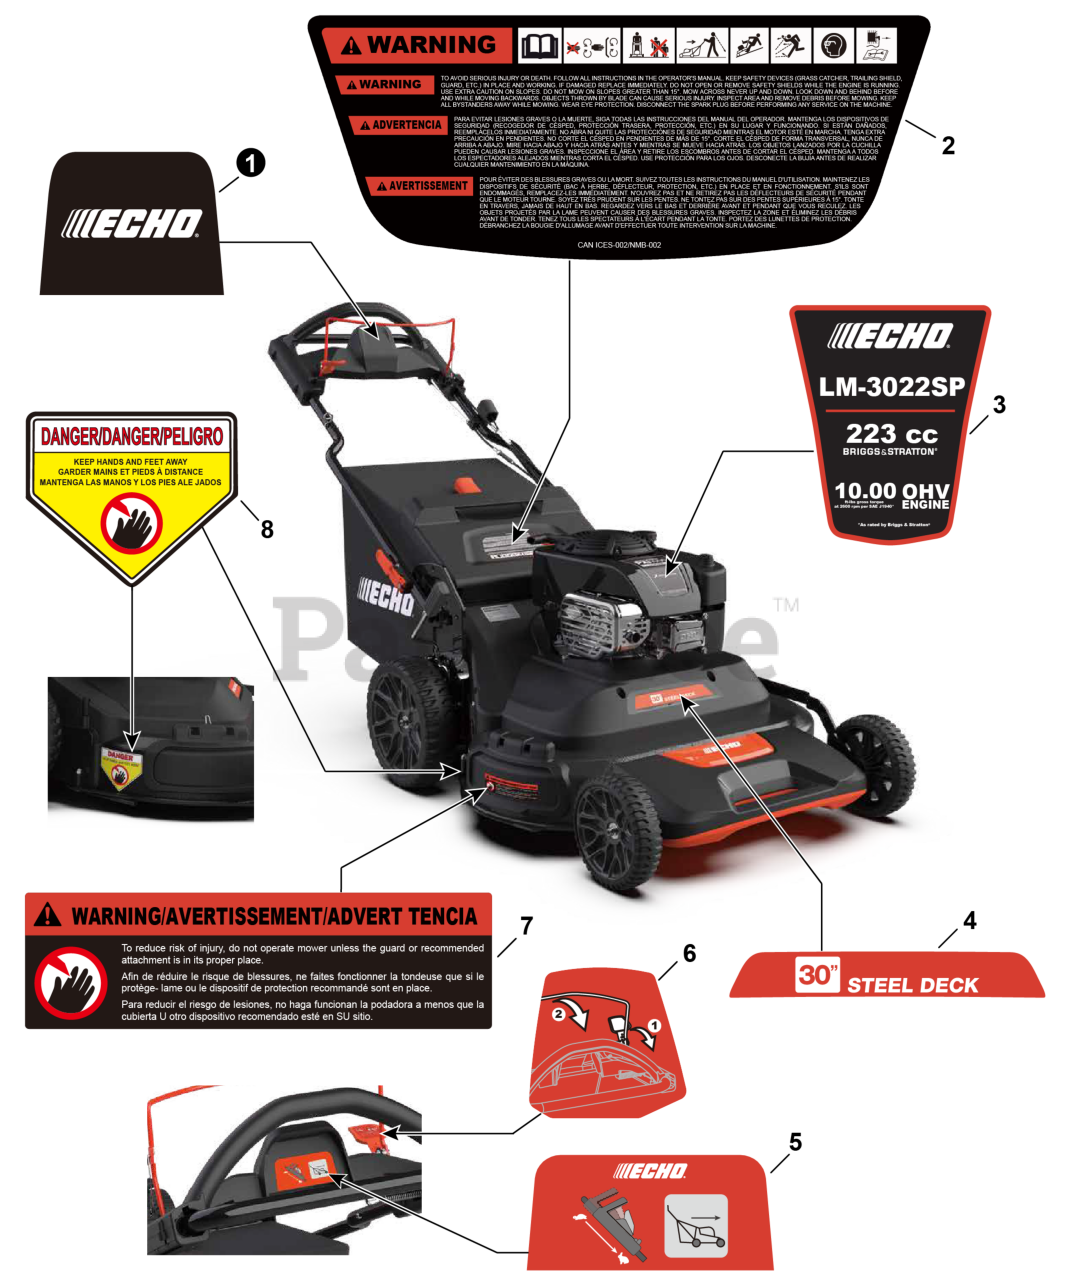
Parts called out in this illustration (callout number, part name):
1	LABEL, BRAND
2	LABEL, REAR COVER WARNING
3	LABEL, MODEL
4	LABEL, 30" STEEL DECK
5	LABEL, SELF-PROPEL
6	LABEL, INTERLOCK LEVER
7	LABEL, WARNING
8	LABEL, DANGER
